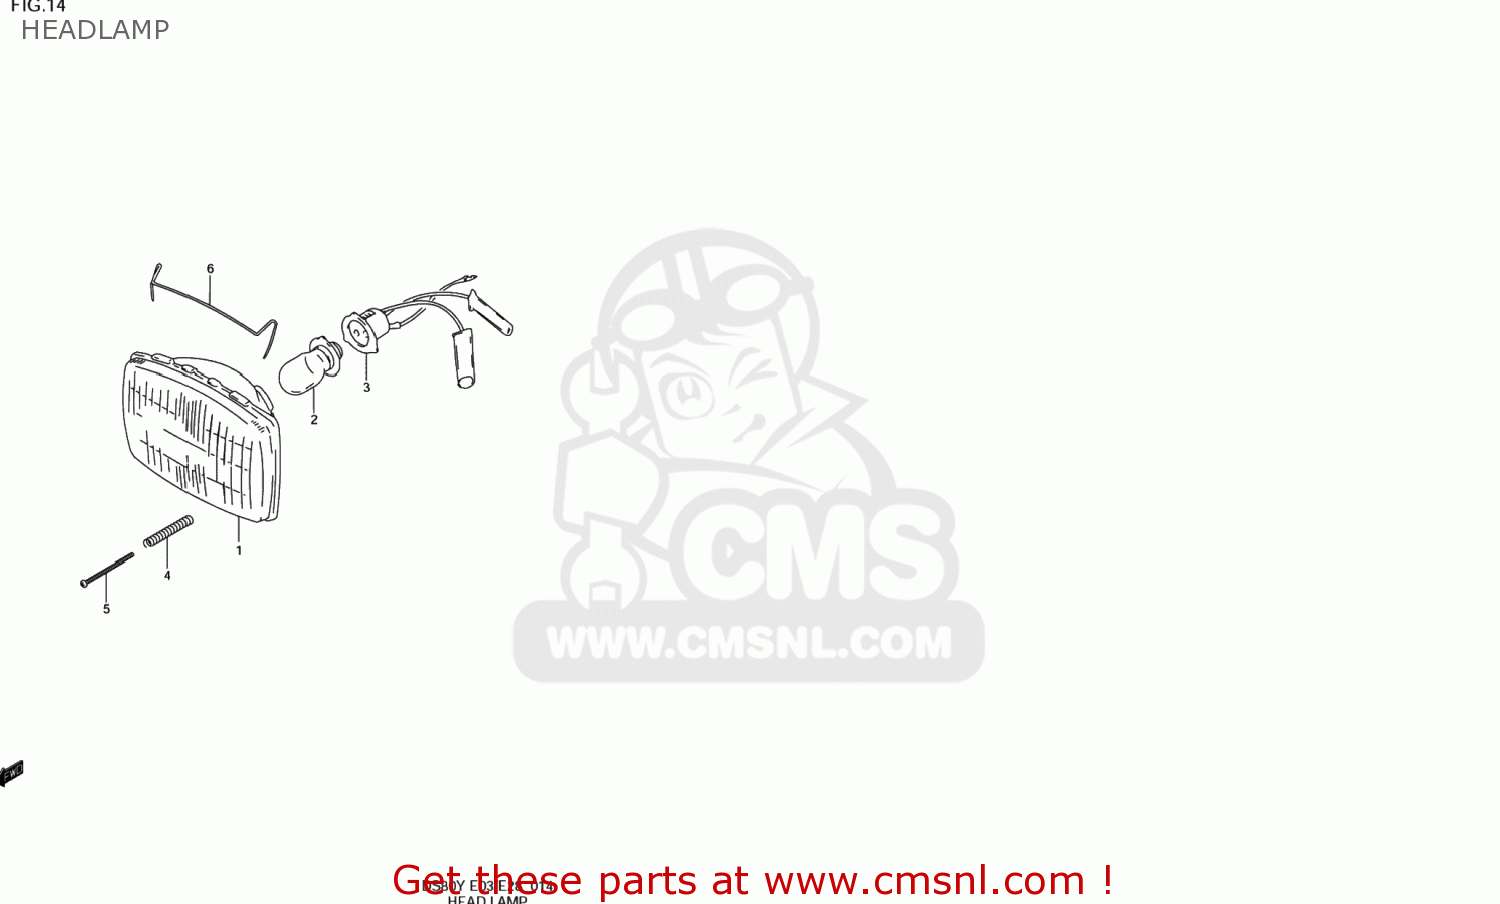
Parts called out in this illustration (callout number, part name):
1	LAMP UNIT
2	BULB(6V15/15W/STANLEY,A3598HA)
3	SOCKET,HEADLAMP
4	SPRING,HEAD LAMP ADJUSTER
5	SCREW
6	SPRING,SUPPORT
